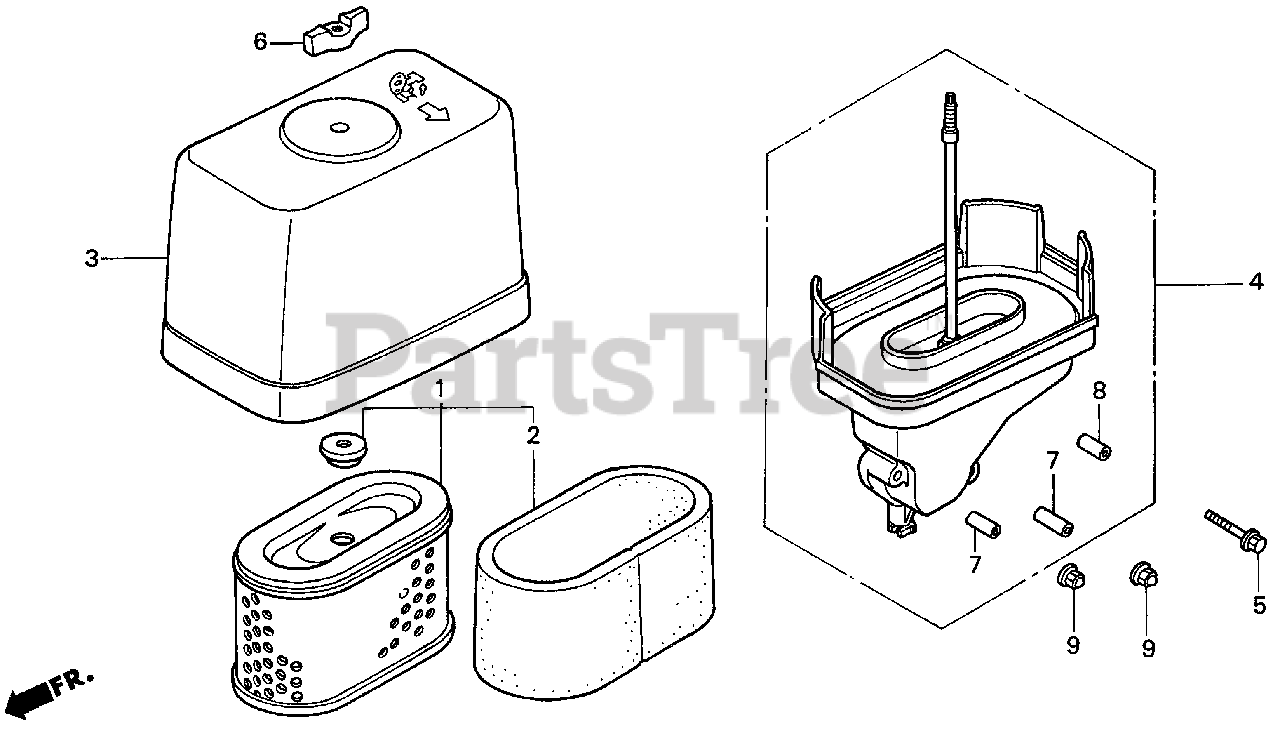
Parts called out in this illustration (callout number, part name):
1	ELEMENT, AIR CLEANER (PLASTIC BASE)
2	FILTER (OUTER)
3	COVER, AIR CLEANER
4	ELBOW, AIR CLEANER
5	BOLT, FLANGE (6X35)
6	WINGNUT, TOOL BOX SETTING
7	COLLAR, AIR CLEANER
8	COLLAR, AIR CLEANER
9	NUT, FLANGE (6MM)
